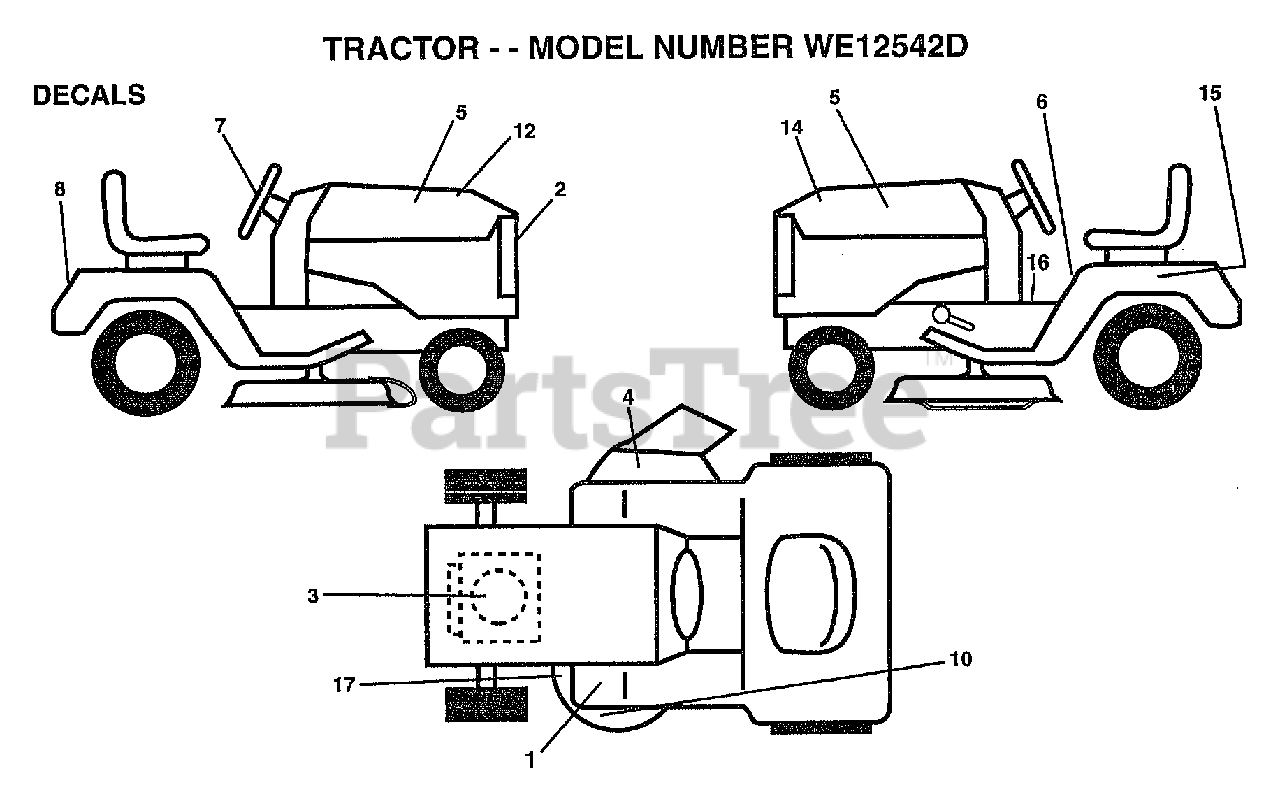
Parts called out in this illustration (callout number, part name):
1	DECAL T
2	DECAL, GRILLE LENS
4	"DECAL, WARNING"
5	DECA, PNL SD
6	DECAL.CAUT.ENG/FR
7	DECAL, INS STRG WH
8	DECAL.FENDER.LOGO
10	DECAL, DECK GRASSEATER
12	DECAL.HOOD.RH.
14	DECAL.HOOD.LH
15	DECAL.BATRY.3-3908
16	"DECAL.OPER,SDL"
17	"DECAL-SCHEM,BELT"
